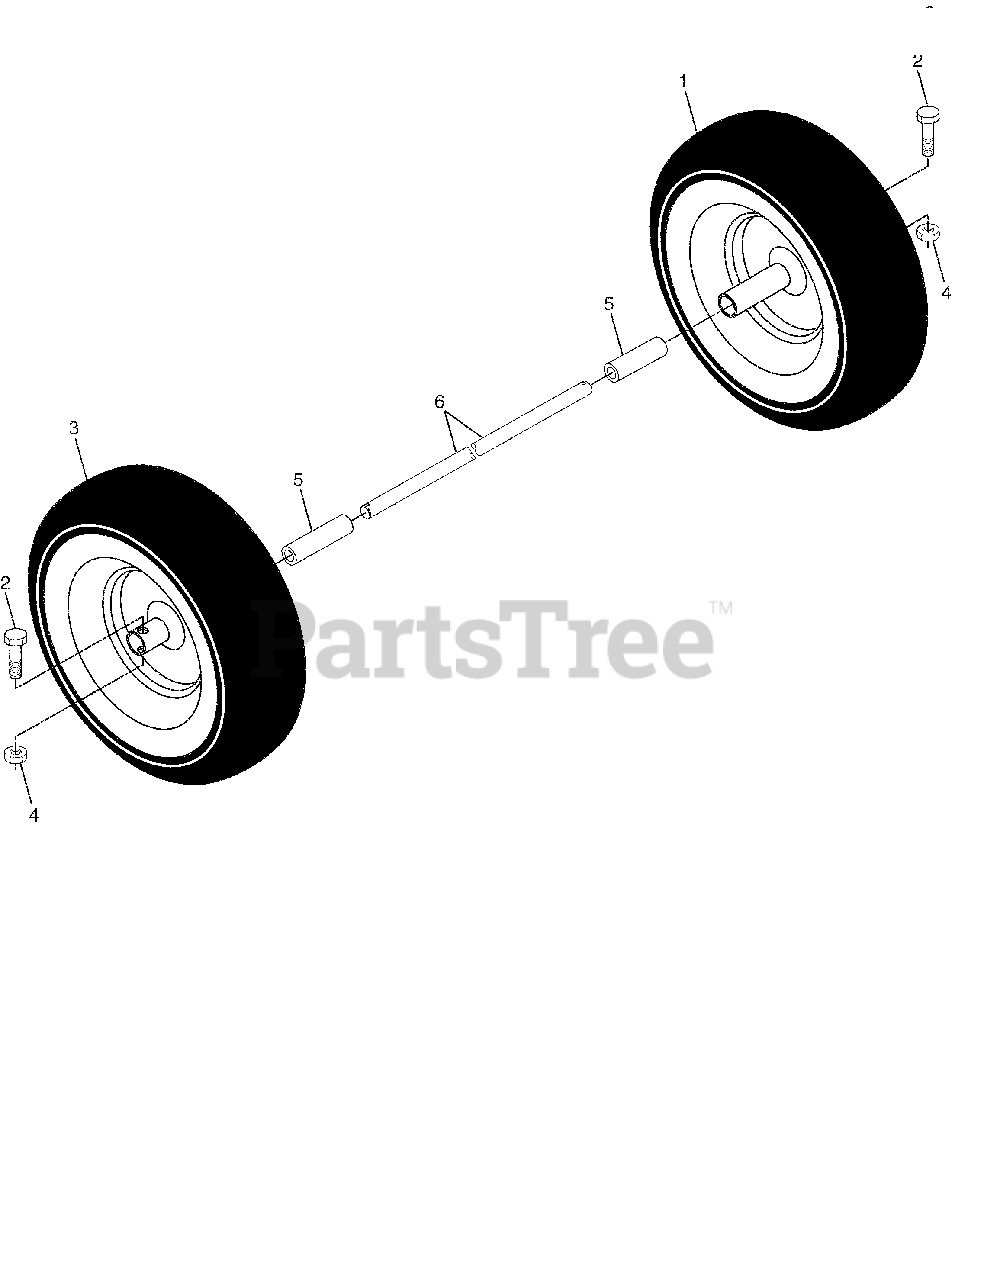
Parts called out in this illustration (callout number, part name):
1	Wheel Assembly, 16", Power Steering, LH
2	Screw, Hex Head
3	Wheel Assembly, 16", Power Steering, RH
4	Nut, Hex
6	Tube, Axle
